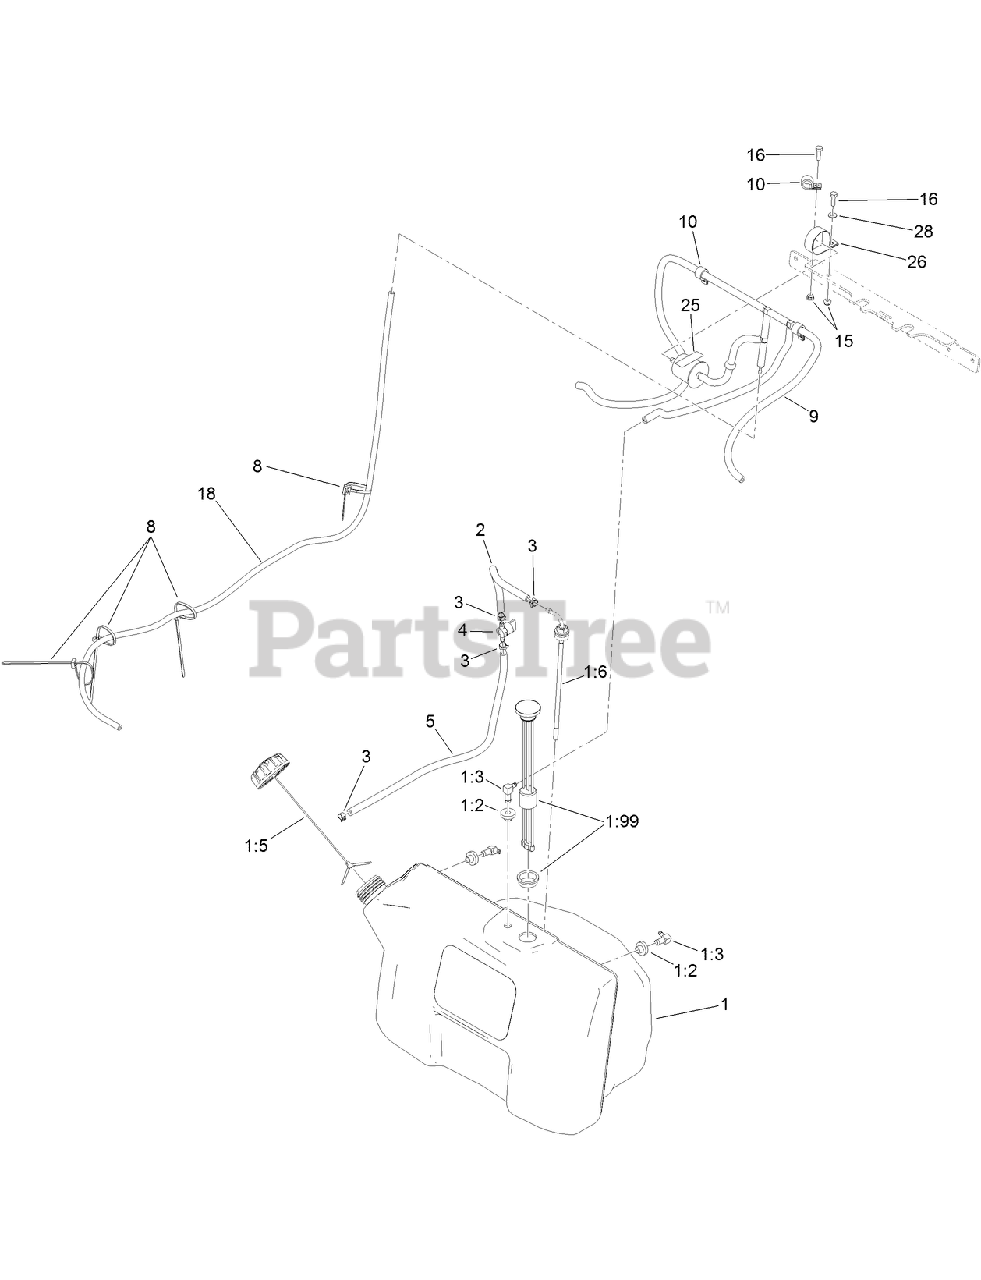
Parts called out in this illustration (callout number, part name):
1	TANK ASM
1:2	BUSHING
1:3	ELBOW-90 DEG
1:5	CAP-FUEL, RATCHETING
1:6	FITTING-FUEL, BULKHEAD
1:99	FUEL GAGE REPLACEMENT KIT
2	HOSE-FUEL
3	CLAMP-HOSE
4	VALVE-FUEL
5	HOSE-FUEL
8	TIE-CABLE
9	VENT HOSE ASM
10	CLAMP-CABLE
15	NUT-HF
16	SCREW-HH
18	HOSE-FUEL
25	DECAL-FILTER, EMISSIONS
26	CLAMP-R
28	WASHER-FLAT
